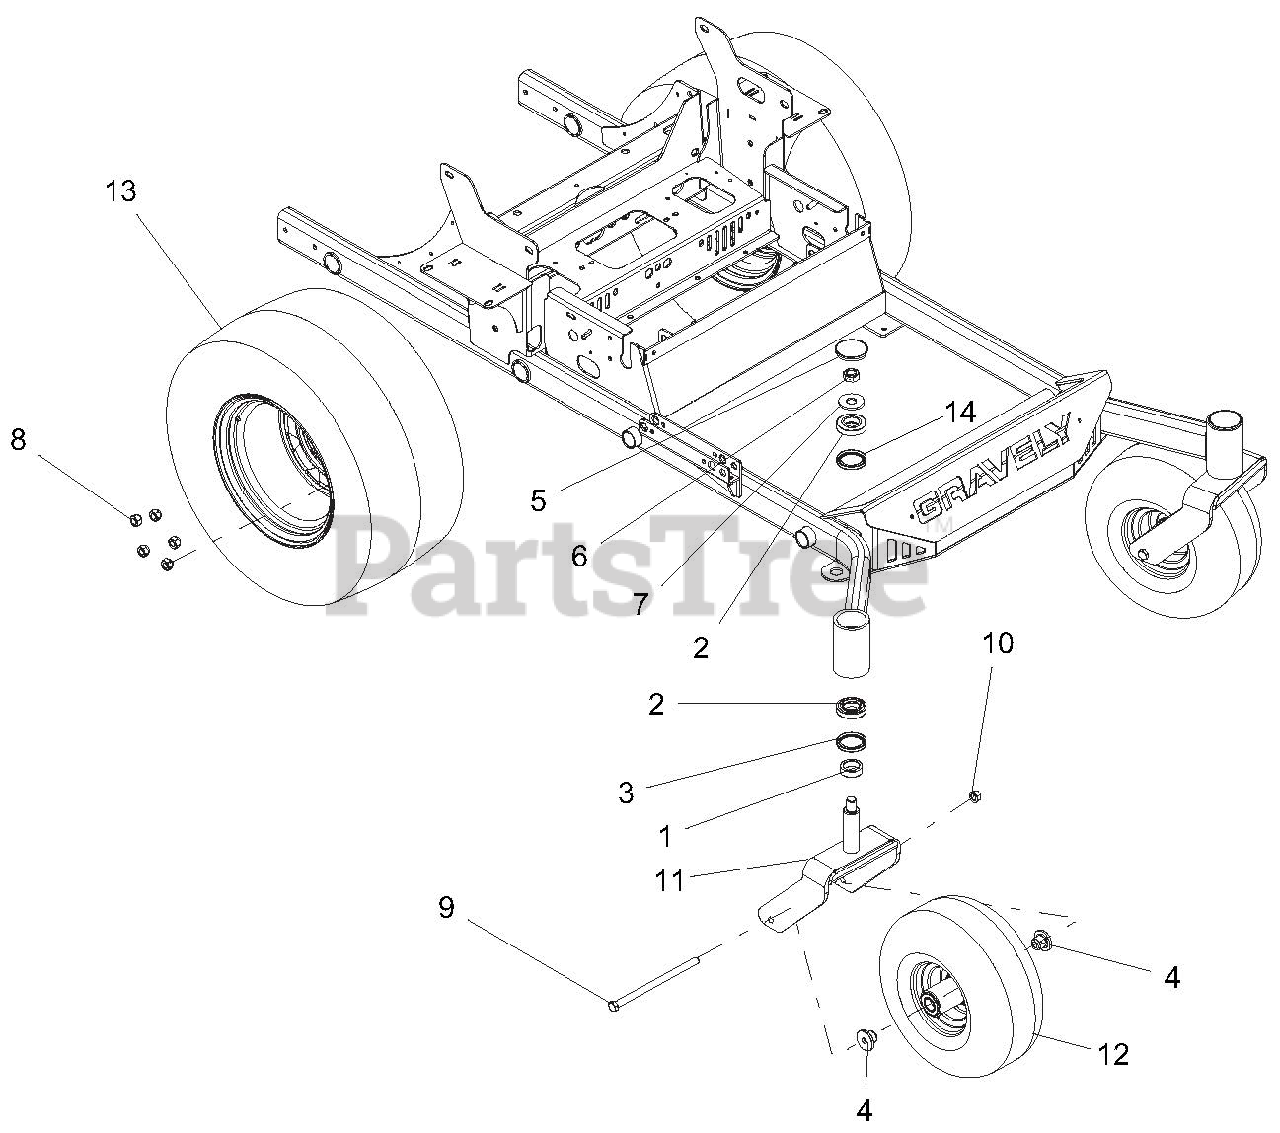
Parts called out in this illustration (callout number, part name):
1	SPACER-1.258 ID X 1.750 OD X .550
2	ROLLER BEARING
3	SEAL, OIL 1.75 X 2.332 X .312
4	SPACER, FRONT WHEEL
5	CAP, DUST
6	NUT-LK-CTR-JAM .75-16 YWZC
7	WSHR-FL-STL.812X2.00X.148YWZC
8	NUT, 1/2-20 LUG C
9	BLT-HEX .50-13X9.00 GR5 YWZC
10	NUT, LK-TOP-FLG .50-13 YWZC
11	WMT, CASTER FORK
12	TIRE/WHEEL 15 X 6-6 SEMI PNEU
13	TIRE/WHEEL ASSY, 24X11.50-12
13	TIRE, 24X11.50-12
13	TIRE/WHEEL ASSM, 23X10.00-12
13	TIRE, 23X10.00-12
14	BEARING CONE 1.25 X .66
